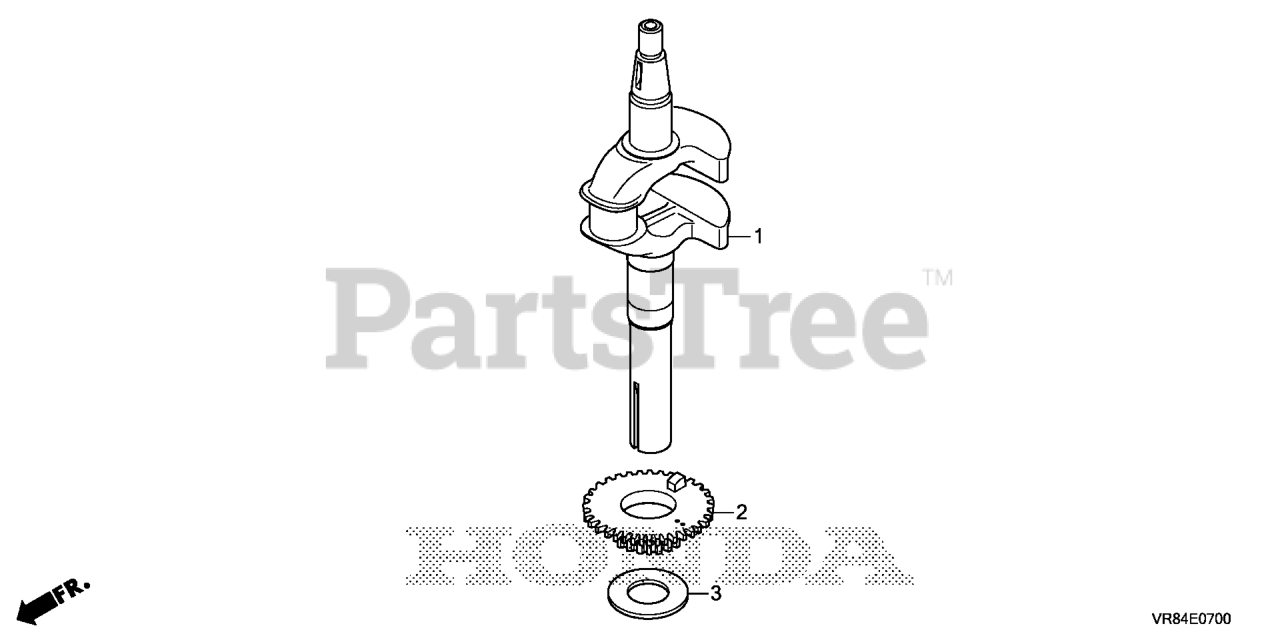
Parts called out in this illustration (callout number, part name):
1	CRANKSHAFT (N3-TYPE)
2	GEAR, TIMING
3	WASHER, THRUST
